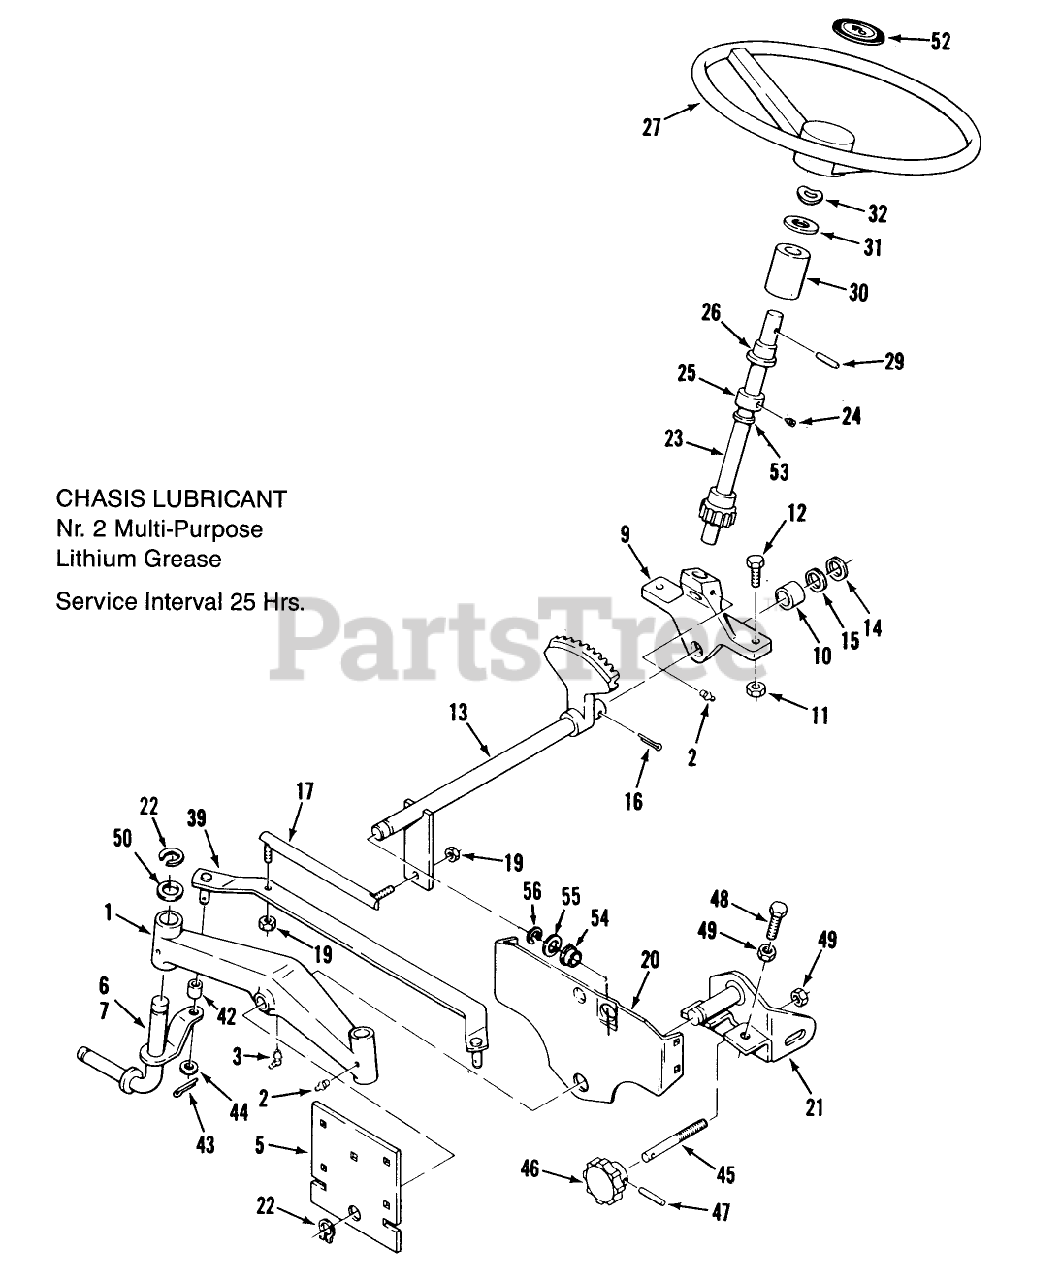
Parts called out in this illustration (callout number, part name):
3	FITTING-GREASE
10	BEARING-BRONZE
14	WASHER-SHIM
15	WASHER
21	ASSY-FRT HANGER *R
26	BEARING-FLANGED
30	TUBE-STEERING
31	WASHER-FLAT
32	WASHER-BOWED
44	WASHER-FLAT
46	KNOB-ADJUSTMENT
47	PIN-ROLL
49	NUT-HEX, JAM
50	WASHER
53	RING-RETAINING
54	BUSHING
55	WASHER SPECIAL
